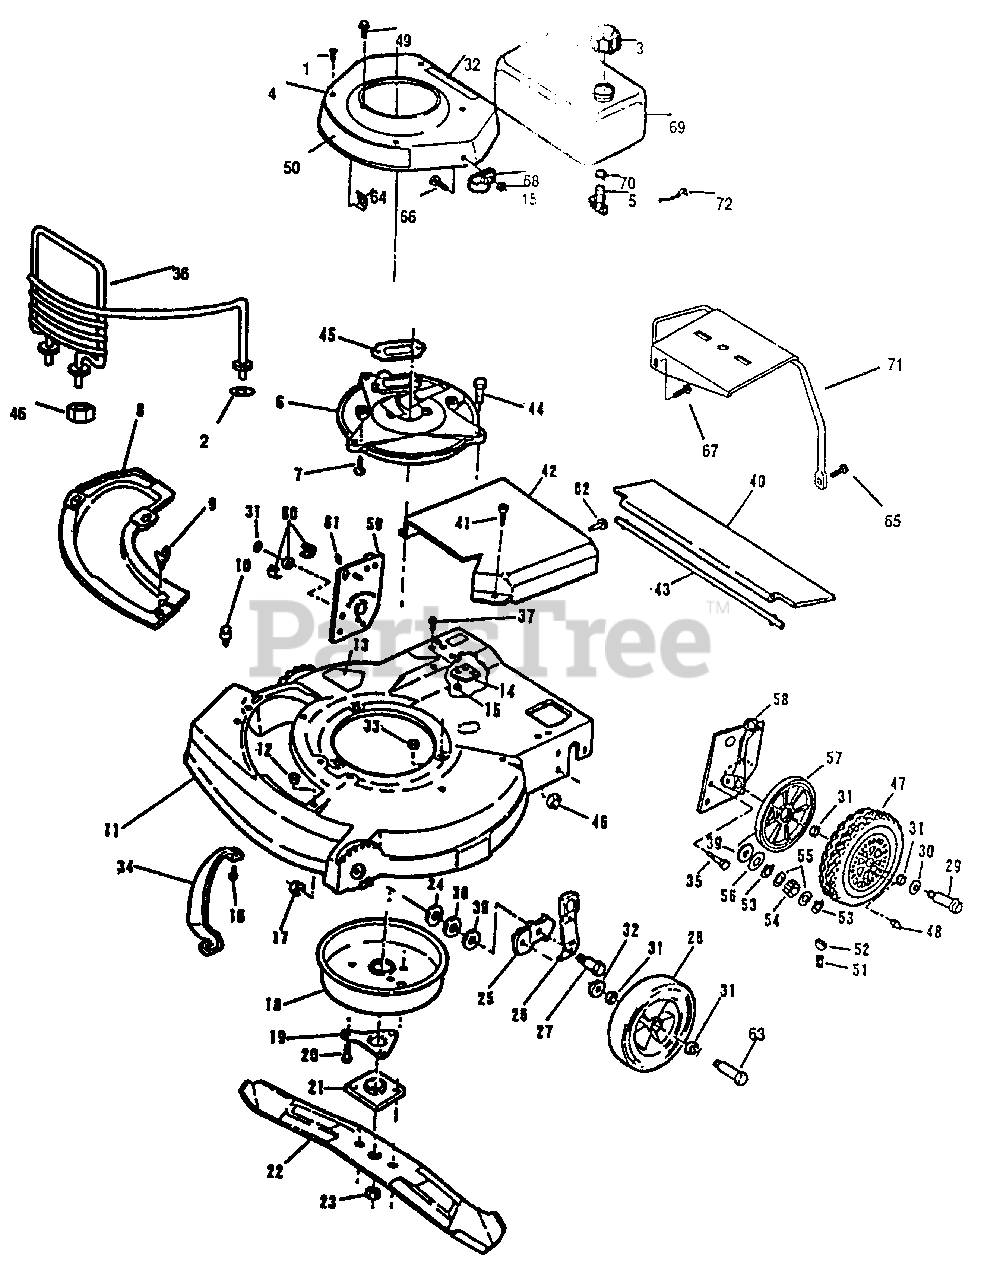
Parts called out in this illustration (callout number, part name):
1	Screw
2	Washer
3	Fuel Cap
4	Shroud-Engine
5	Vent & Screen Assembly
6	Plate Muffler
7	Screw-Muffler Plate to Block
8	Cover Plate
9	Wing Screw
10	Screw-Plate and Chute Mounting
11	Housing Assembly
12	Grommet
13	Decal-Blade Contact Warning
14	Bolster-Housing
15	Nut-Bolster to Housing
16	Screw
17	Nut
18	Muffler Cover Assembly
19	Support-Crankshaft
20	Screw-Muffler to Muffler Plate
21	Collar and Plate Assembly
22	Blade-21"
23	Nut-Blade
24	Washer
25	Bracket-Wheel Height Adjust
26	Knob and Spring Assembly
27	Bolt-Shoulder
28	Wheel-Front
29	Bolt-Wheel
30	Washer-Felt
31	Washer-Felt
32	Decal-Fuel Mixture
33	Nut-Muffler Plate to Housing
34	Toe Bar
35	Screw-Handle Bracket
36	Screw-Shroud to C.D. Bracket
37	Screw-Bolster to Housing
38	Washer-Shim-Wheel Height Adjust Bracket
39	Washer-Shim-Wheel Height Adjust Bracket
40	Shield-Trailing
41	Screw-Drive Cover Mounting
42	Cover-Drive
43	Rod-Trailing Shield
44	Screw-Muffler Plate to Housing
45	Gasket-Exhaust
46	Locknut-Hdl. Brkt. to Housing
47	Rear Wheel
48	Lube Fitting
49	Screw-Starter Mounting
50	Applique
51	Spring
52	Key
53	Retaining Ring
54	Pinion
55	Spacer
56	Washer
57	Cover-Rear Wheel
58	Height Adjuster Assembly-L.H.
59	Height Adjuster Assembly-R.H.
60	Bearing and Retainer Assembly
61	Fitting
62	Screw
63	Bolt
64	Retainer-Applique
65	Screw-Fuel Tank Support
66	Screw
67	Screw
68	Clamp
69	Fuel Tank
70	Clamp
71	Fuel Tank Bracket
72	Spring-Fuel Tank Mounting
